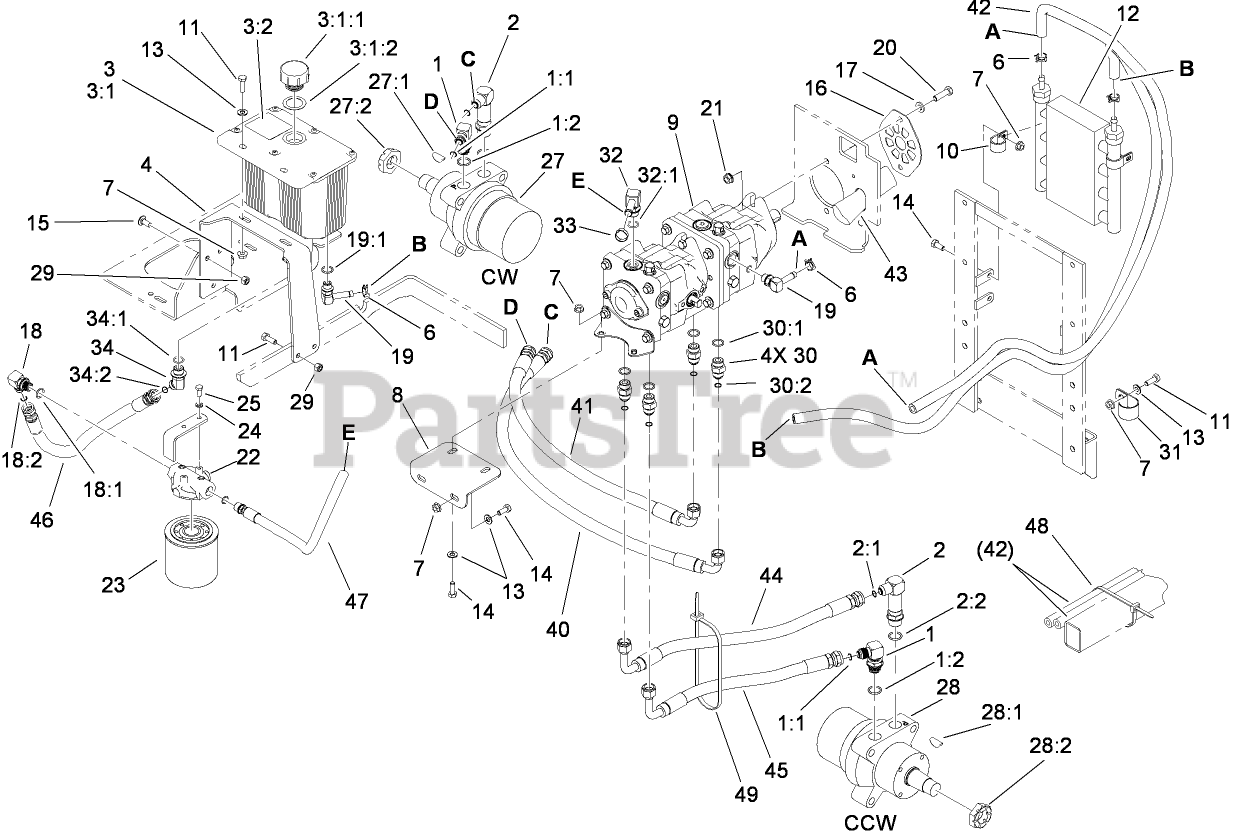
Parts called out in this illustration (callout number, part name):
1	FITTING-HYD, 90 DEG
1:1	O-Ring
1:2	O-RING
2	FITTING-ELBOW-90
2:1	O-Ring
2:2	O-RING
3	HYDRAULIC TANK ASM
3:1	TANK-HYDRAULIC
3:1:1	CAP-RESERVOIR, HYD
3:1:2	GASKET-CAP
3:2	DECAL-TANK, HYD
4	BRACKET-TANK, HYDRAULIC
6	CLAMP-HOSE
7	NUT-HF
8	BRACKET-PUMP, FRONT
9	TANDEM PUMP ASM
10	R-CLAMP
11	SCREW-HH
12	COOLER-OIL, HYDRO
13	WASHER-PLAIN
14	SCREW-HH
15	SCREW-CARR
16	PLATE-SHIELD, PUMP
17	WASHER-FLAT
18	FITTING-90 DEG
18:1	O-RING
18:2	O-Ring
19	FITTING-ELBOW, 90
19:1	O-RING
20	SCREW-HH
21	NUT-HHF, WHIZ
22	HEAD-FILTER
23	CARTRIDGE-FILTER, OIL
24	WASHER-LOCK
25	SCREW-HH
27	HYD MOTOR ASM (CCW)
27:1	KEY-WOODRUFF
27:2	NUT-HH
28	HYD MOTOR ASM (CW)
28:1	KEY-WOODRUFF
28:2	NUT-HH
29	NUT-LOCK, NI
30	FITTING-STRAIGHT
30:1	O-RING
30:2	O-Ring
31	CLAMP-R
32	FITTING-ELBOW, 90 DEG
32:1	O-RING
33	CLAMP-HOSE
34	FITTING-HYD, 45 DEG
34:1	O-RING
34:2	O-Ring
40	HYDRAULIC HOSE ASM
41	HYDRAULIC HOSE ASM
42	HOSE-HYDRAULIC
43	SLEEVE-FABRIC
44	HYDRAULIC HOSE ASM
45	HYDRAULIC HOSE ASM
46	HYDRAULIC HOSE ASM
47	HYDRAULIC HOSE ASM
48	TIE-PLASTIC
49	CABLE TIE-PLASTIC
